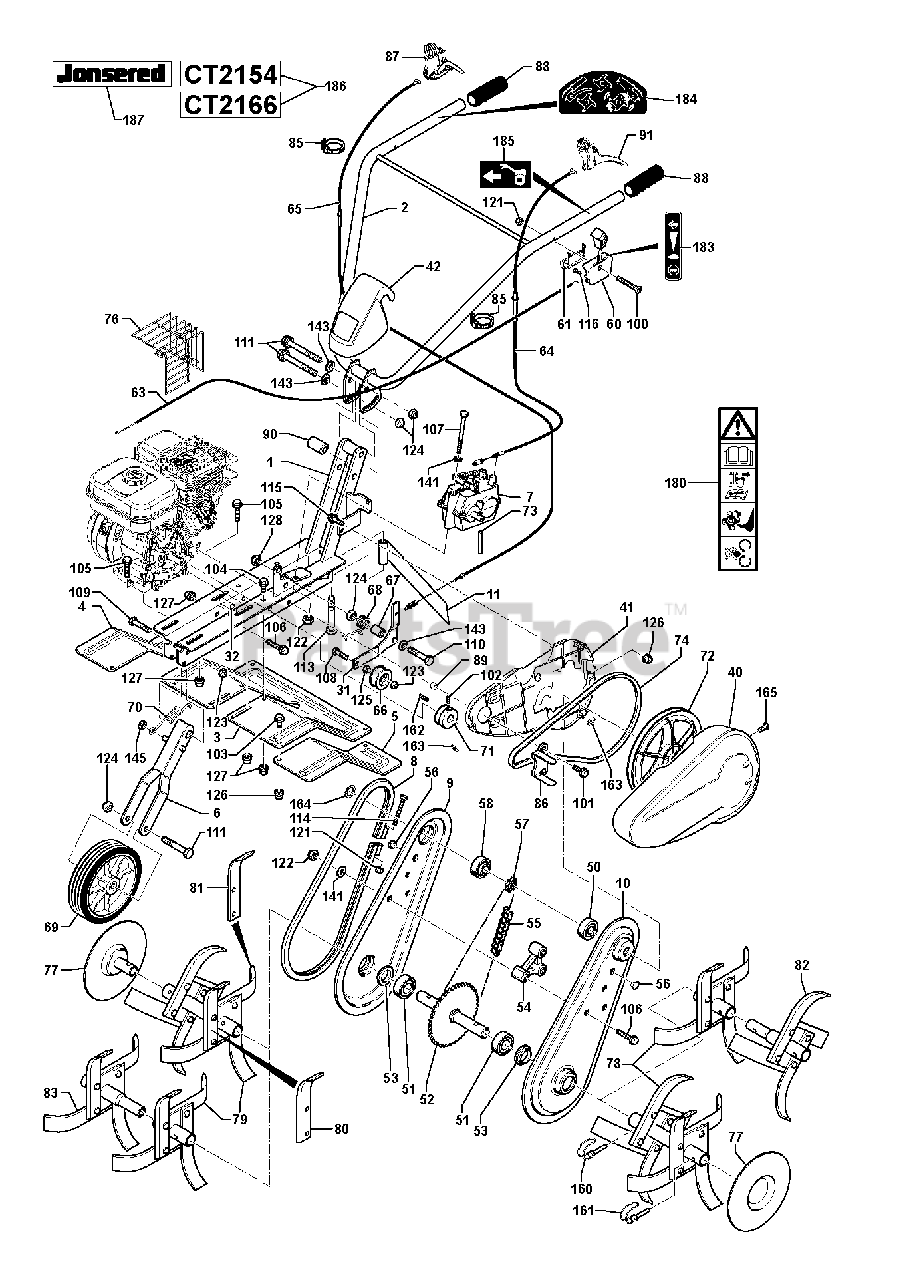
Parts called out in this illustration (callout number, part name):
50	BEARING
52	GEAR
54	BRACKET
55	DRIVE CHAIN
61	THROTTLE CONTROL
69	WHEEL
70	SPRING
88	HANDLE
124	SCREW NLA
183	DECAL NLA
